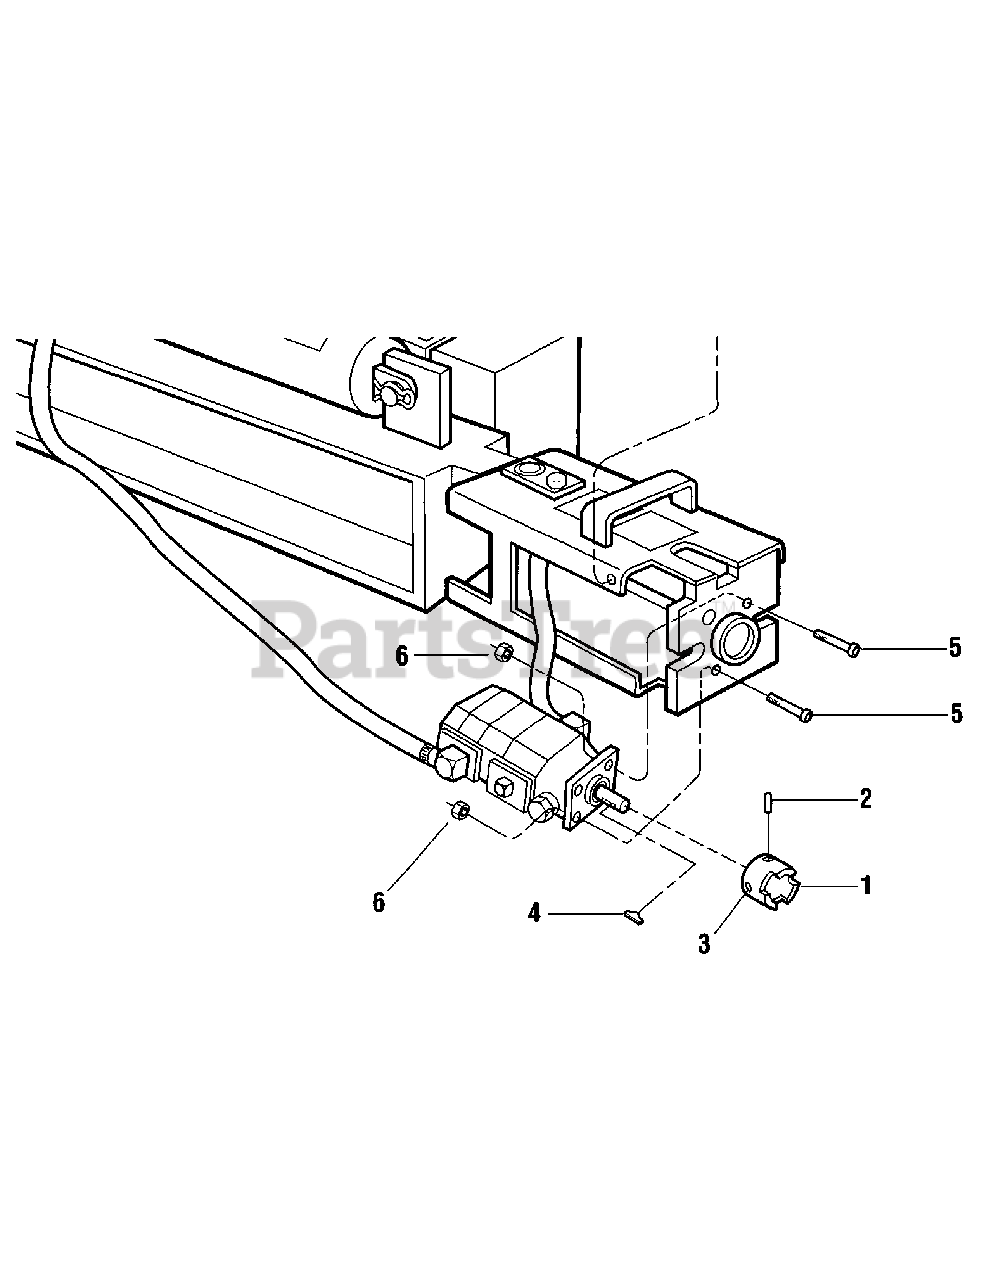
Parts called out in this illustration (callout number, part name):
1	Clutch (Includes Ref. 2 & 3)
2	Set Screw-Clutch Assembly
3	Spiral Pin-Clutch Assembly
4	Hi Pro Key-Clutch Assembly
5	5/16"-18 x 1" Cap Screw
6	Hex Nut 5/16" - 18
